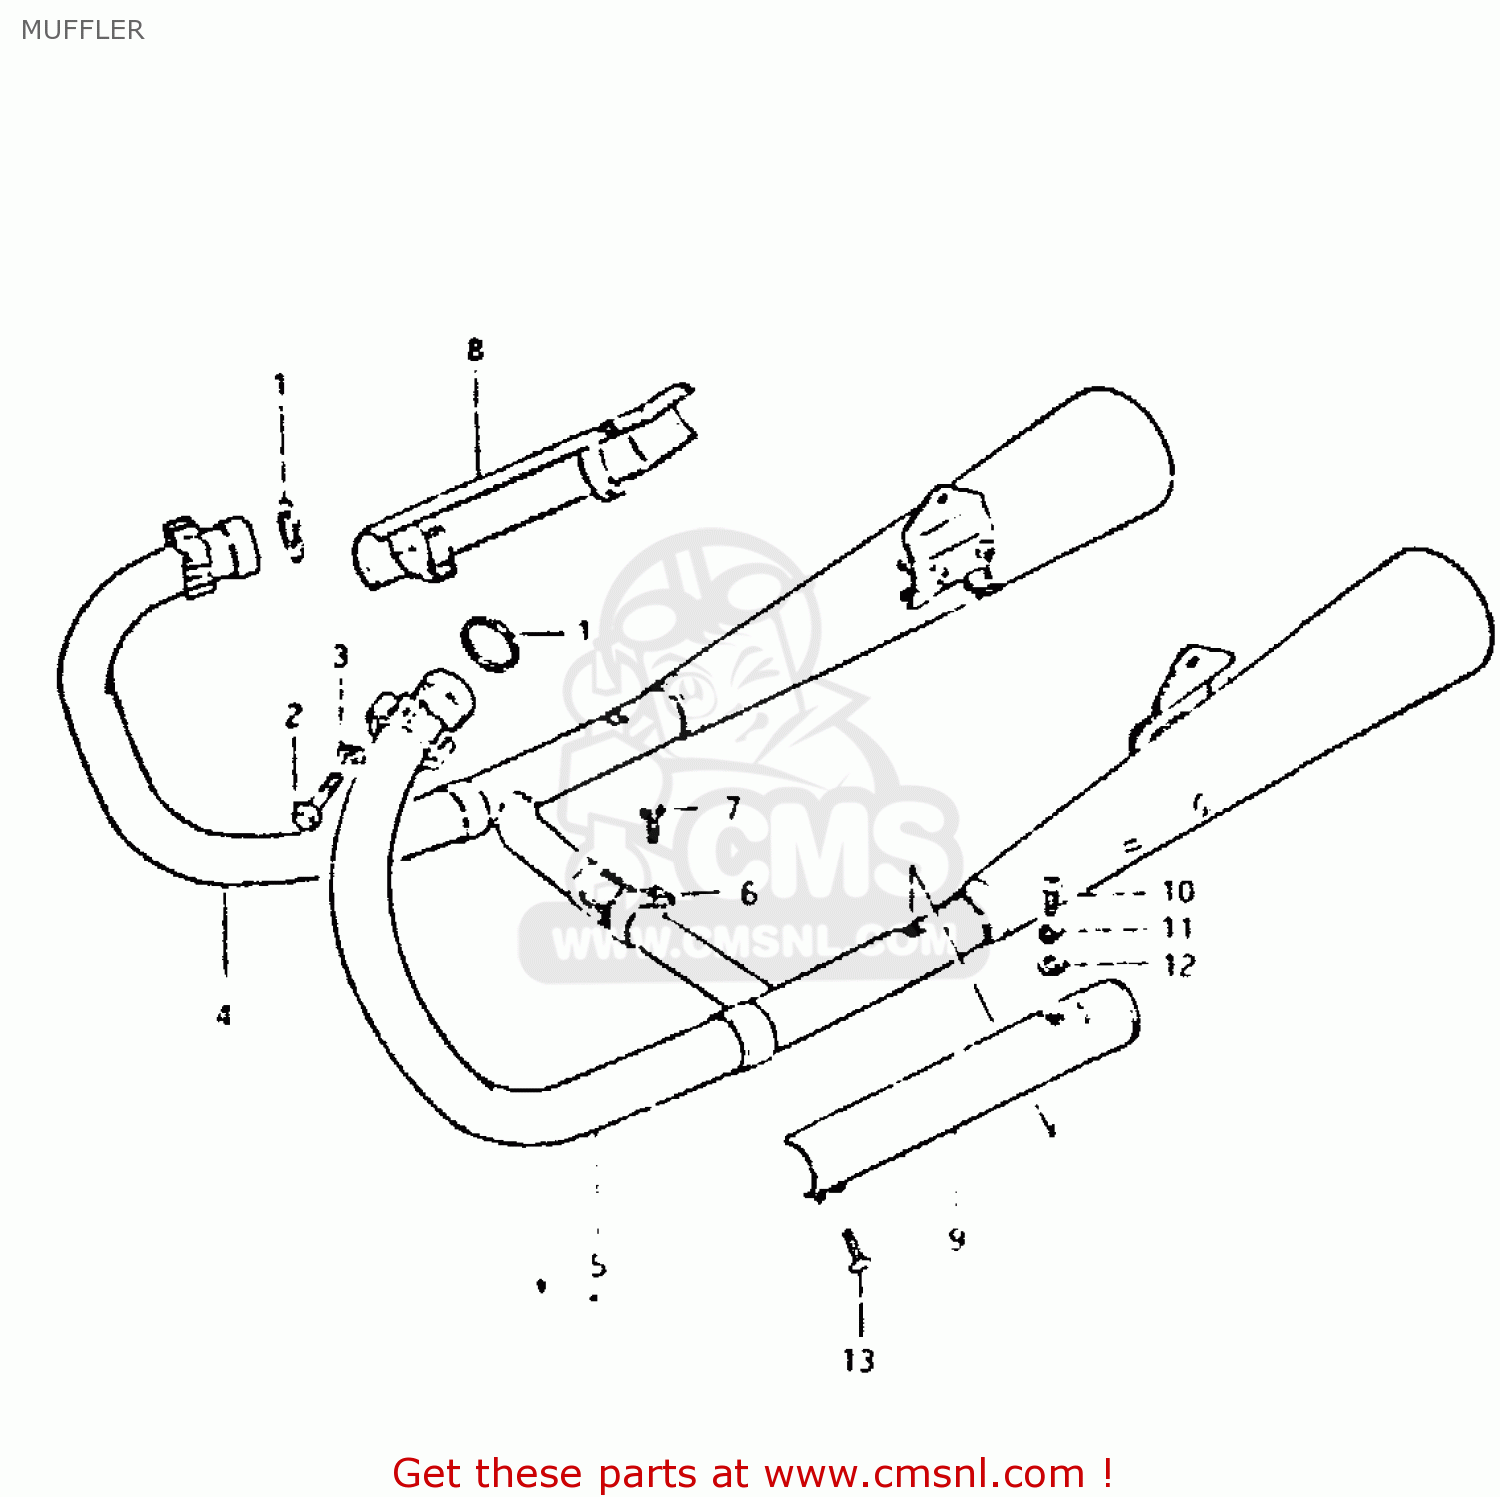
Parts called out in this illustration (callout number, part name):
1	GASKET,EXHAUST PIPE (NAS)
2	BOLT
3	LOCK WASHER
4	MUFFLER, RH
5	MUFFLER, LH
6	CLAMP
7	BOLT
8	COVER,MUFFLER
9	COVER,MUFFLER
10	SCREW
11	LOCK WASHER
12	WASHER
13	SCREW
